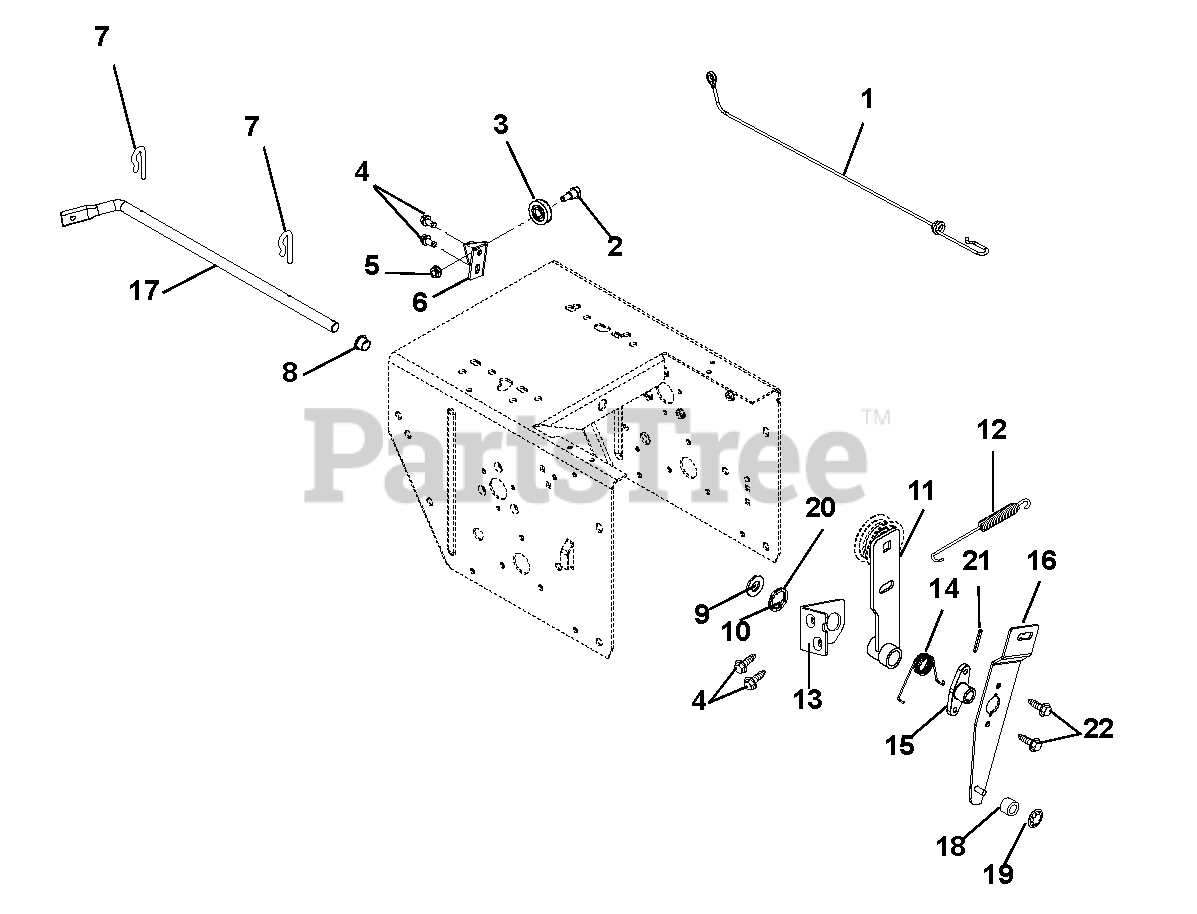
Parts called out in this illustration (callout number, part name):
1	CABLE, LOWER TRACTION,SS & PRO
2	BOLT, SHLDR-.375X.375X.25-20
3	PULLEY, CABLE
4	SCR-TAP .25-20X.50 HWH TR YWZ
5	@NUT-LK-TOP-FLG .25-20 YWZC
6	BRACKET, CABLE PULLEY
7	CLIP, SPRING
8	BUSHING, POLYLINER-.50 SPLIT
9	@WSHR-FL-STL.531X1.06X.095YWZC
10	BSHG,FLANGE .500X.625X.270X.75
11	ARM, IDLER-TRACTION
12	SG-TENS .06X.482X5.35
13	BRACKET, SUPPORT
14	SG-TORS .067X.88
15	HUB, BRAKE ARM
16	ARM, IDLER-ATTACHMENT
17	ARM, ATTACHMENT
18	BSHG,SLV .265 X .625 X .375
19	RG-RTNG-EXT .250X.010
20	WAVE SPRING .600X.875X.25FH
21	PIN-ROLL .125X1.00
22	SCR-TAP .25-20X.75 HWH TR YWZ
